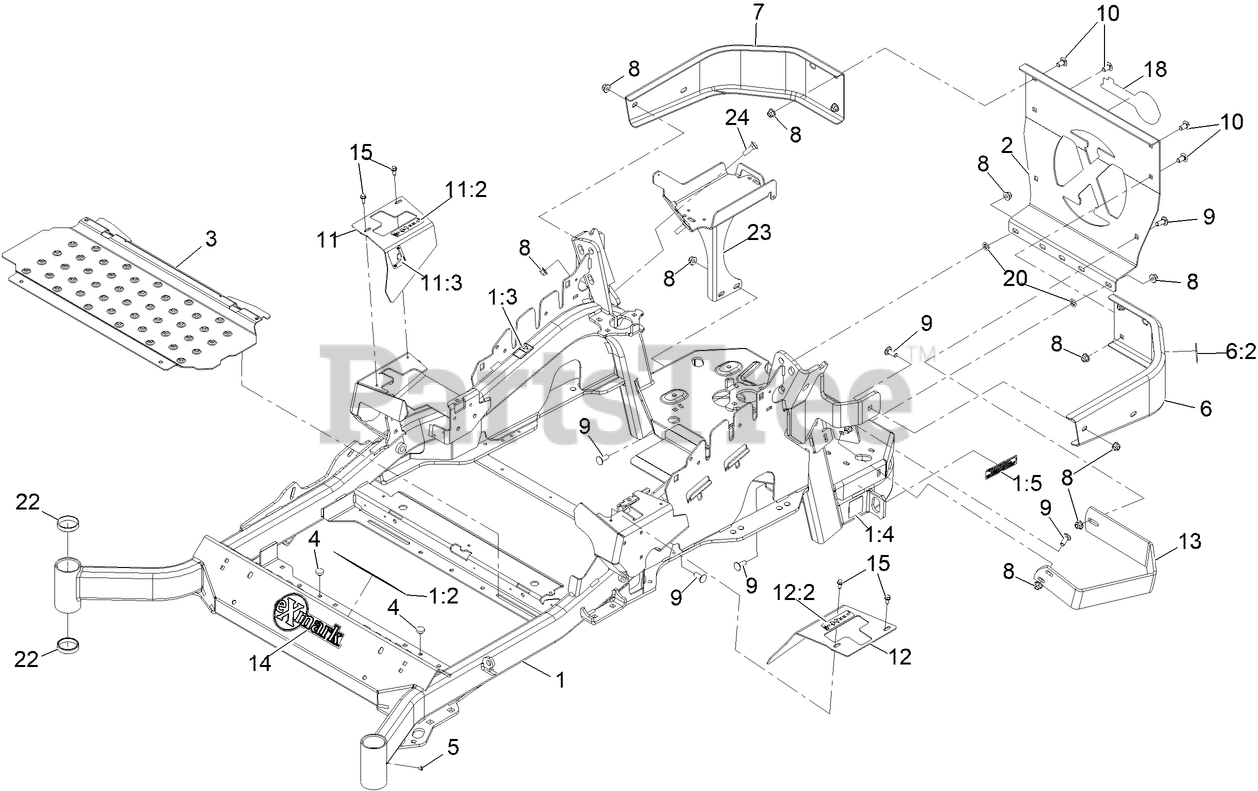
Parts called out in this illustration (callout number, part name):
1	MAINFRAME SERVICE ASM - 60
1:2	DECAL-DANGER
1:3	DECAL-WARNING
1:4	DECAL-HAZARD, PINCHED FINGER
1:5	DECAL-ARRESTOR, SPARK
2	PLATE,REAR GUARD
6	LH BUMPER ASM
6:2	DECAL-WARNING
7	BUMPER-RH
8	NUT-HF, NI
9	SCREW-CARR
10	SCREW-CARR
11	RH MOTION CONTROL COVER ASM
11:2	DECAL-CONTROL, MOTION
11:3	DECAL-PARK BRAKE, CE
12	LH MOTION CONTROL COVER ASM
12:2	DECAL-CONTROL, MOTION
13	GUARD-MUFFLER
14	DECAL-EXMARK
15	SCREW-HWH
18	DECAL, EXMARK LOGO
20	NUT-PUSH
22	CUP-BEARING
23	BATTERY MOUNT ASM
24	BOLT-CARR
